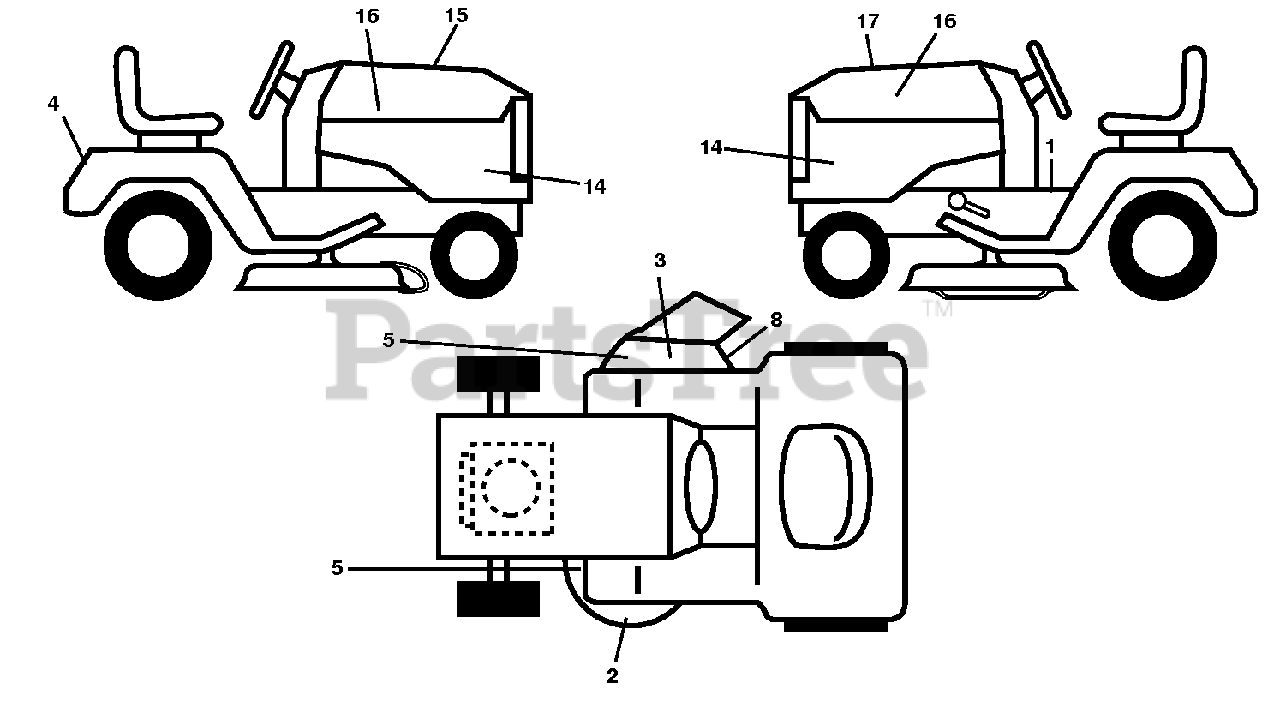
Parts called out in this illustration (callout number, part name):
1	DECAL.WARN.STARTINST.LOWEARIEN
2	Deck Decal, 48"
3	DECAL.TRACT/ZTR.DECKWARN.HUSQ
4	DECAL.FENDER
5	DECAL.DECK.CLEARCUT.NOSTEP
8	DECAL.MOWER.SCH.48/54.PREM
14	Tractor Side Panel Decal
15	DECAL.WARNING.CUST.RESP.E85.
16	DECAL.BADGE.170MM.TEXTLOGO.
17	Decal, Replacement Kohler KT7 TGB 54F
